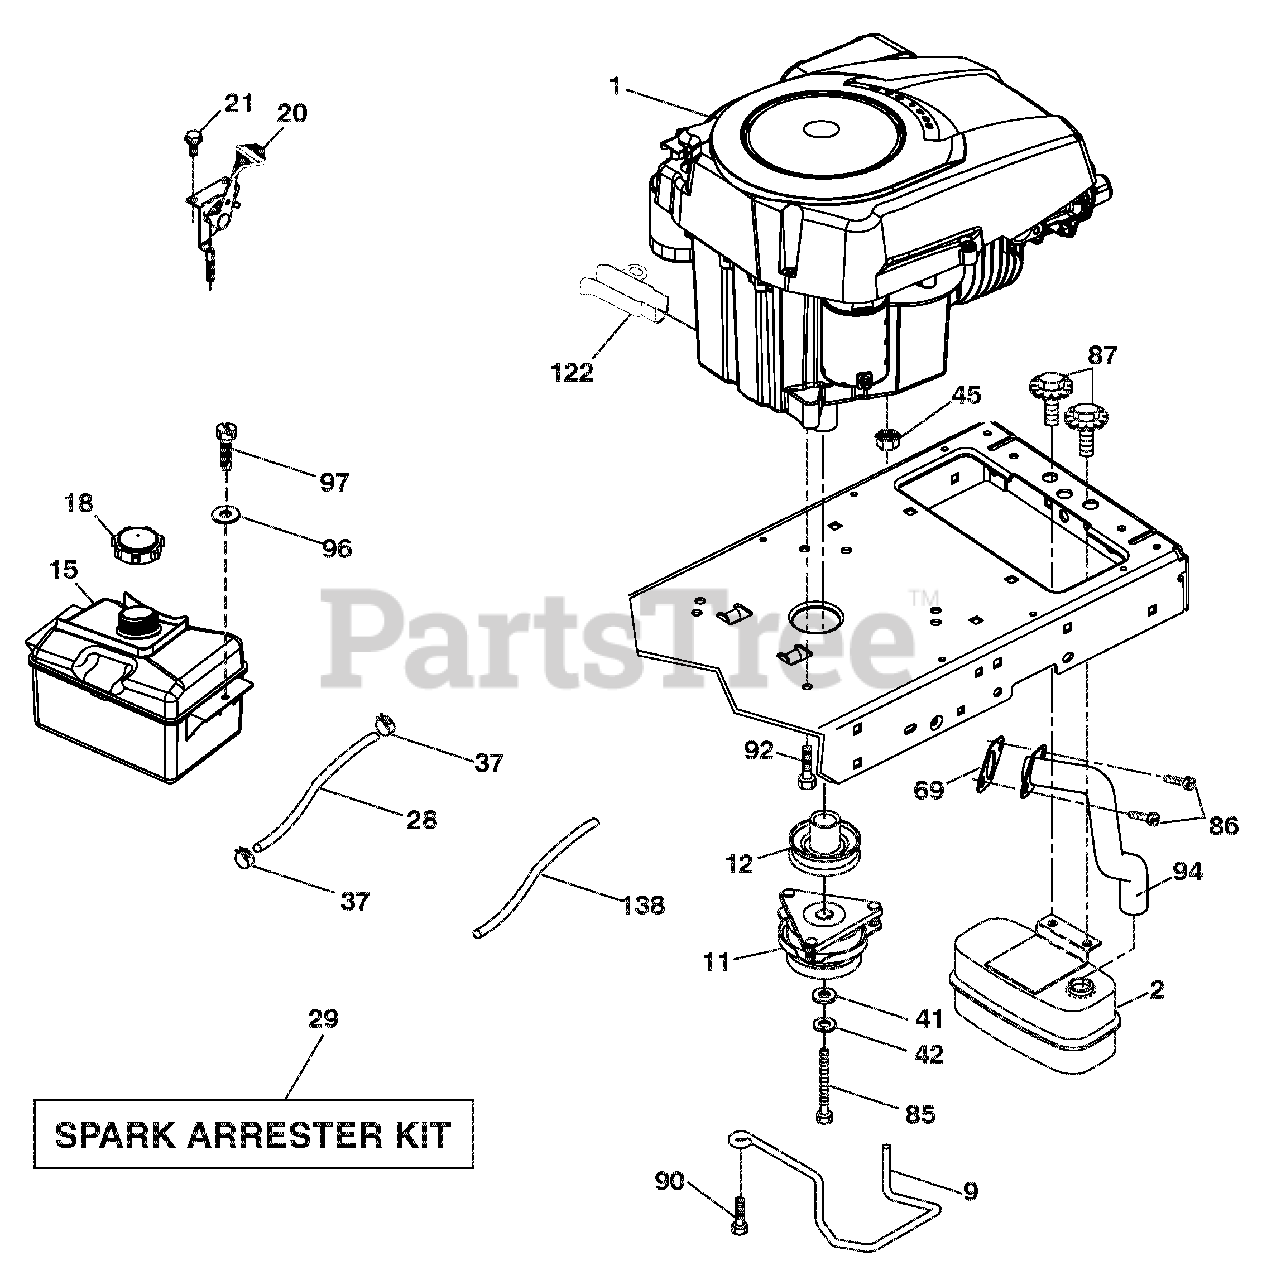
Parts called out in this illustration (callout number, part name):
1	ENGINE KOHL MOD NO. SV590-0218
2	MUFFLER.SINGLE.CYL.KOHL.COURAG
9	KEEPER.BELT.ENGINE.4.25"NSTG
11	CLUTCH OGURA
12	PULLEY.ENGINE.TUFFTORQE.1"CRK.
15	TANK.FUEL.2.5.GAL.
18	CAP FUEL
20	CONTROL THROTTLE/CHOKE
28	LINE.FUEL.22"FRONT.EMIS.CA.LP
29	KIT.SPARK ARRESTOR(392390 B&S)
37	CLAMP.HOSE.BLK.
41	WASHER.1-1/2 ODX15/32 IDX.250
42	WASHER.LOCK.HVY HLCL.SPR.7/16
45	Nut, Keps Hex 1/4-20 unc
69	GASKET.KOHLER.SV.I.
85	BOLT.HEX.7/16-20X4XGR5-1.5THR.
86	SCREW SOCKET HEAD 5/16-18 X 1
87	BOLT.5/16-18 UNC X 1 W/SEMS.BL
90	SCREW.3/8-16X1.SMGML.TAP/R.BLK
92	SCREW.3/8-16 X 1.SMGML.TAP/R
94	TUBE.EXHAUST.KOHL.COURAGE
96	WASHER.9/32 X 7/8 X 16GA.
97	SCREW.HEXWSH.THDROL.1/4-20X3/4
122	Extension Drain Oil
138	PURGE.LINE.CARB
